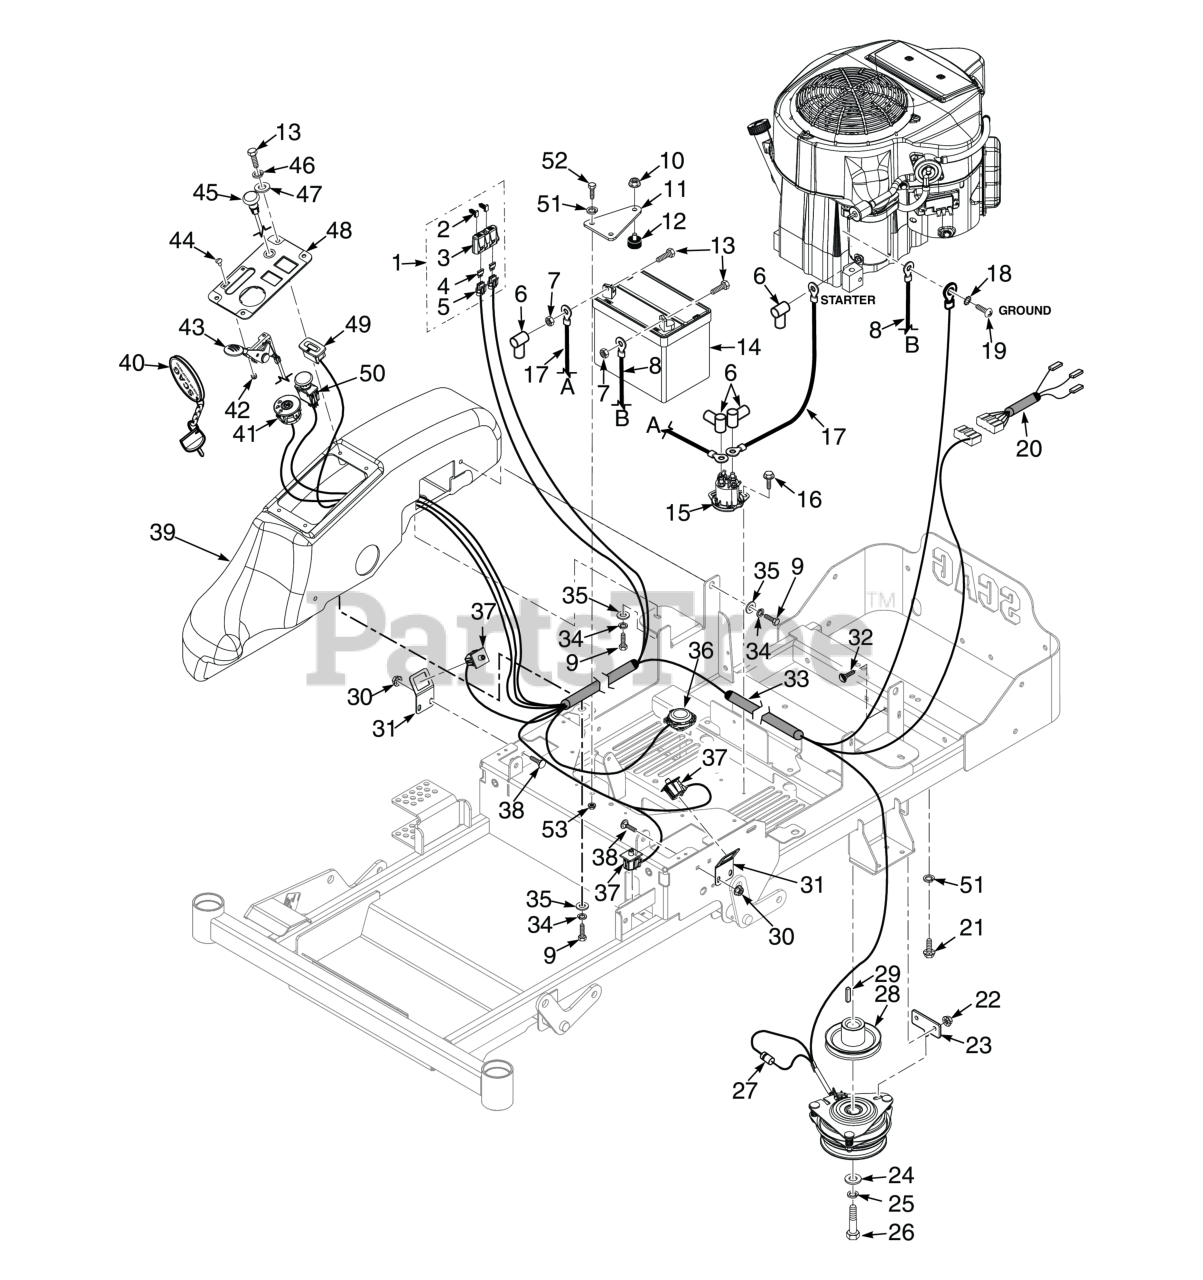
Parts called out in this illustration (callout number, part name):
1	Double Fuse Assy.
2	Clip, Fuse Holder
3	Cover, Sealed Double
4	FUSE, 20 AMP BLADE TYPE AUTOMOTIVE
5	Fuse Holder Assembly
6	RUBBER BOOT
7	Nut, 1/4 - 20 Hex
8	Battery Cable, 31-1/2" Black (25KA, 26DFI, 31DFI) - Kawasaki
9	BOLT, SERRATED FLANGE HEX HEAD 5/16-18 X 3/4"
10	Nut, Serrated Flange 5/16-18 (Right Front Engine Mounting, Briggs and Kohler Only)
11	Battery Hold Down
12	Bumper, Rubber 5/16-18 x 5/8"
13	Bolt, Hex Head 1/4-20 x .5" Battery, (Not Available Through Scag)
14	Battery, 12v - 230CCA
15	Solenoid, Sealed (Briggs & Stratton)
16	Screw, Self-Tapping 1/4-20 x 3/4
17	Battery Cable, 18" Red w/Braid (25KA, 26DFI, 31DFI) - Kawasaki
18	Lockwasher, 5/16" Ext. Tooth (Kohler x1)
19	Bolt, Hex Head M8 - 1.25 x 16 (48V / 52V)
21	Bolt, Hex Head 3/8-16 x 1-1/4", Kawasaki FX / FS
22	Nut, Flange Head Elastic Stop 5/16-18
23	Plate, Anti-Rotation
24	Flatwasher, 7/16-.469 x 1.75 x .25 (48, 52)
25	Lockwasher, 7/16� Spring
26	Bolt, Hex Head 7/16-20 x 3¼" w/Patch
27	Diode, 600V 6 Amp
28	Pulley, 4-1/2" - 1" Bore
29	Key, 1/4 x 1/4 x 1.25" Pulley Mtg.
30	Nut, Flanged Elastic Stop 1/4-20
31	Bracket, Switch
32	Bolt, 5/16-18 x .75 RHSN Carriage
33	Wire Harness
34	Lockwasher, 5/16 (.317 x .586 x .078) Helical Spring
35	Flatwasher, 5/16-.375 x .875 x .083 (35BV & 37BV-EFI)
36	Switch, Double Pole - Twist
37	Switch, Double Pole - Plunger
38	Serr. Fl. Hex Head CPSCR, 1/4-20 x 3/4"
39	Console Tank w/Decals, SZL-36
40	Key, Assembly w/Fob
41	Ignition Switch
42	Nut, Elastic Stop #10-24
43	Throttle Control, Kawasaki
44	Bolt, Carriage #10-24 x 1/2"
45	Choke Control, Kawasaki
46	Lockwasher, 1/4� Spring
47	Flatwasher, 1/4" (.312 x .750 x .065")
48	Instrument Panel w/Decal, SZL-36
49	Hour Meter, Inductive
50	Switch, PTO - 10 Amp
51	Lockwasher, 3/8" Spring, Kawasaki FX / FS
52	Bolt, Hex Head, 3/8-16 x 1 Gr. 5
53	Threaded insert, Hex Head (Pressed)
